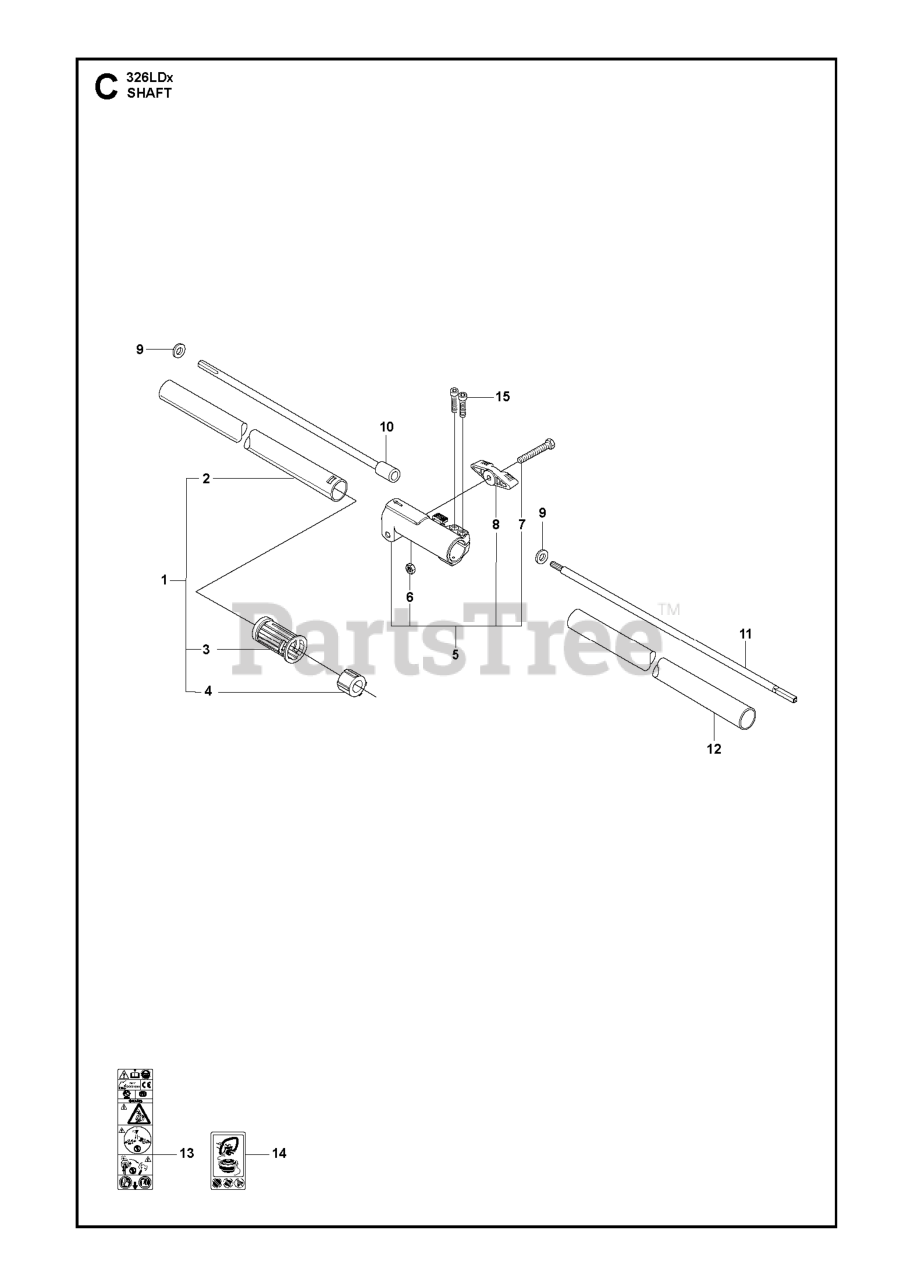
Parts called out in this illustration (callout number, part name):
1	%TUBE ASSY COMPLETE
4	BUSHING
5	CLAMPING SLEEVE
7	BOLT FLANGE
10	SHAFT LOWER
13	RP WARNING DECAL
14	DECAL WARNING "NO BLADES"
15	BOLT FLANGE
